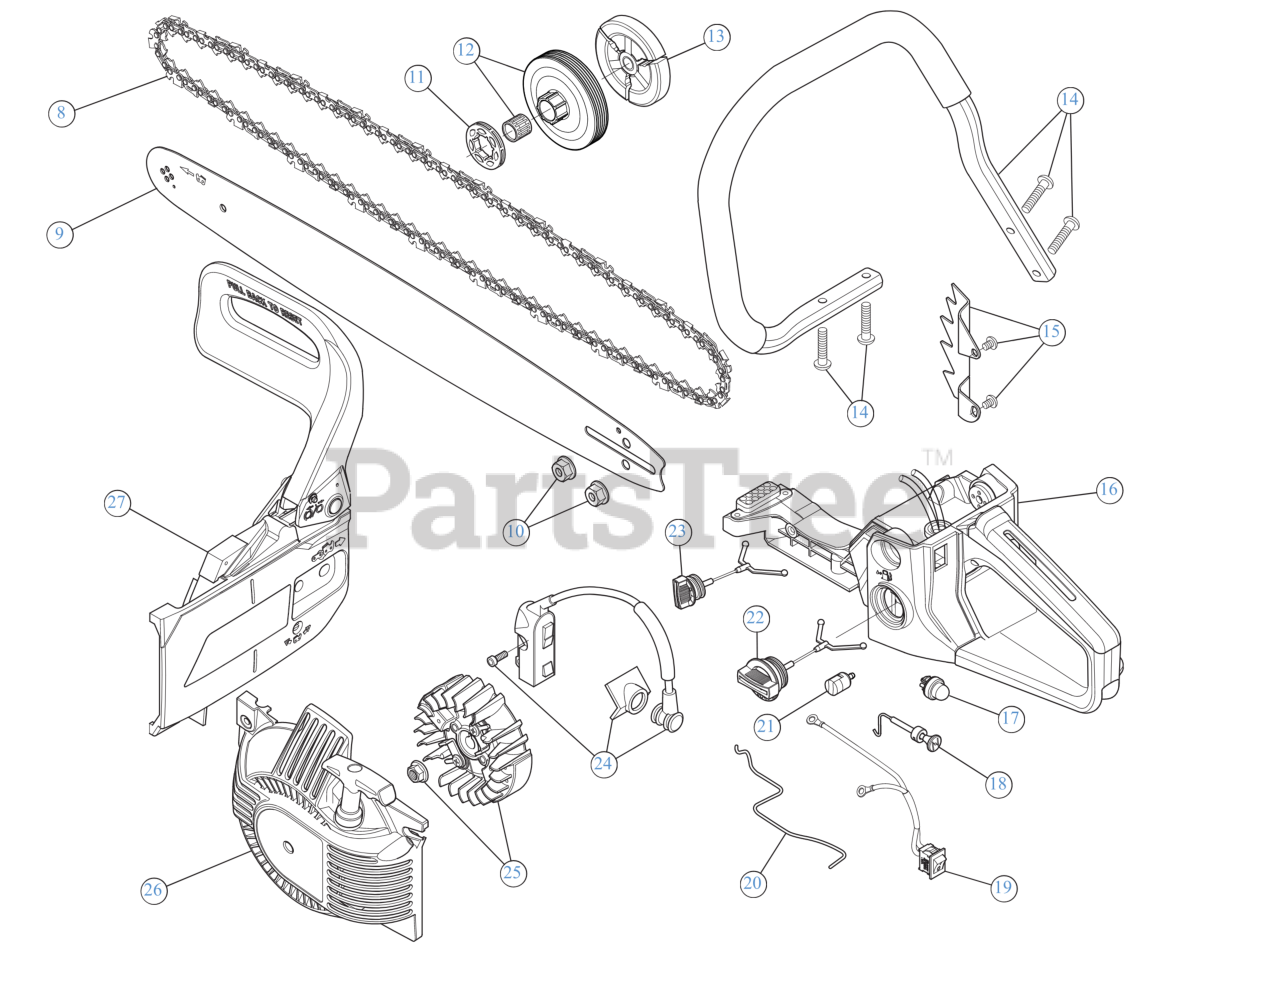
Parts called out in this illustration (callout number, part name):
8	CHAIN:14" TRILINK
8	CHAIN: 16" TRILINK
8	CHAIN 18" TRILINK
9	BAR: 14" TRILINK
9	BAR: 16" TRILINK
9	BAR 18" TRILINK
10	BAR NUT M8
11	SPROCKET
12	CLUTCH DRUM ASSEMBLY
13	CLUTCH ASSEMBLY
14	HANDLE ASSEMBLY
15	SPIKE PLATE W/HDW
16	FUEL HOUSING ASSEMBLY
17	PRIMER BULB YD2500-18410
18	CHOKE LEVER ASSEMBLY
19	SWITCH ASSEMBLY
20	THROTTLE ROD
21	FUEL FILTER YD4600-18034
22	FUEL CAP ASSEMBLY
23	OIL CAP ASSEMBLY
24	MODULE
25	FLYWHEEL
26	STARTER HOUSING ASSEMBLY
27	BRAKE ASSEMBLY:CHAINSAW
